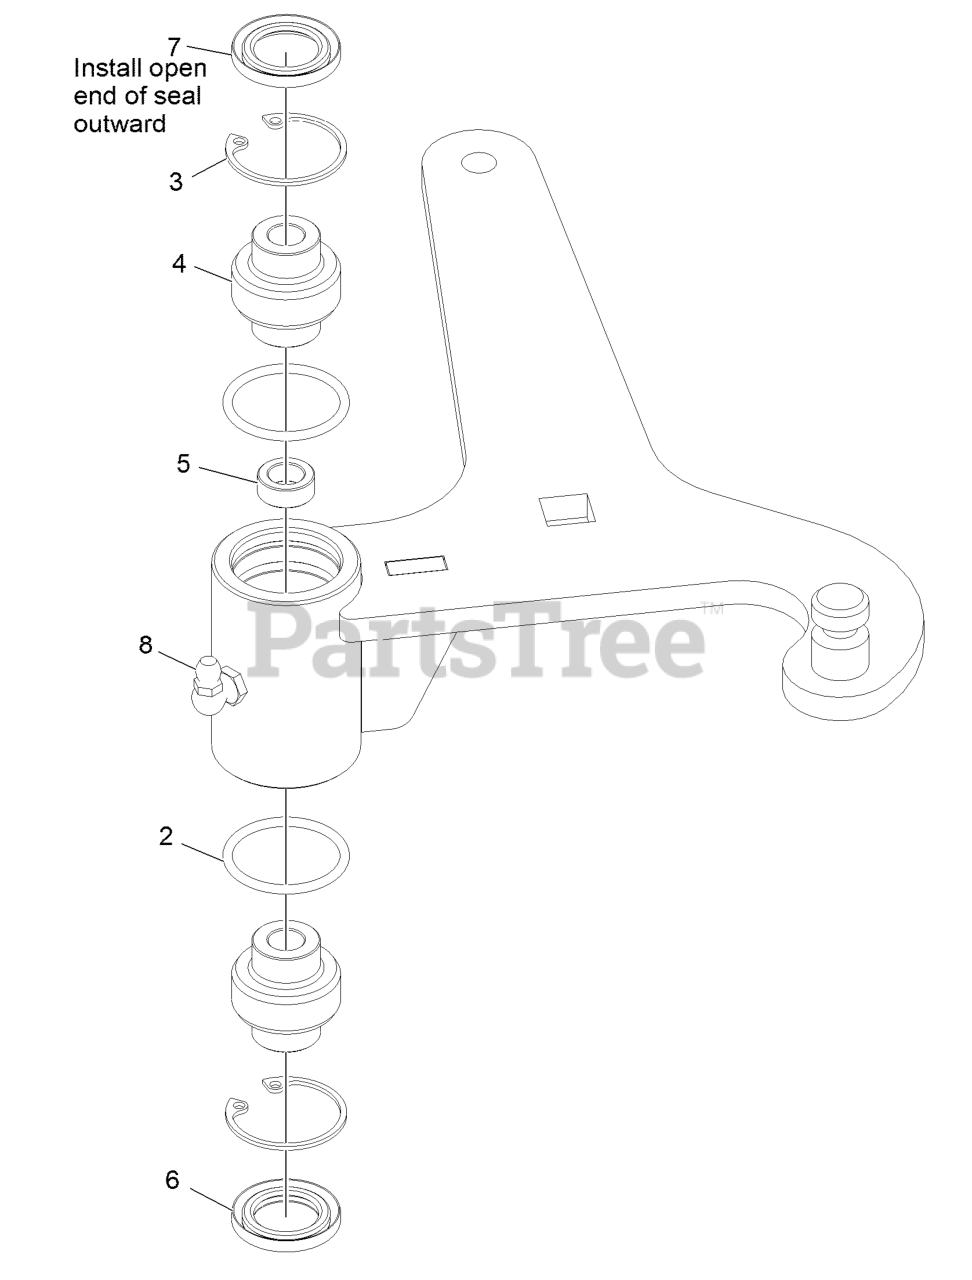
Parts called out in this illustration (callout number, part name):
3	Ring-Snap
4	Bearing-Spherical
6	Seal-Lip, Double
7	Seal-Lip, Single
8	Fitting-Grease, 90 DEG
